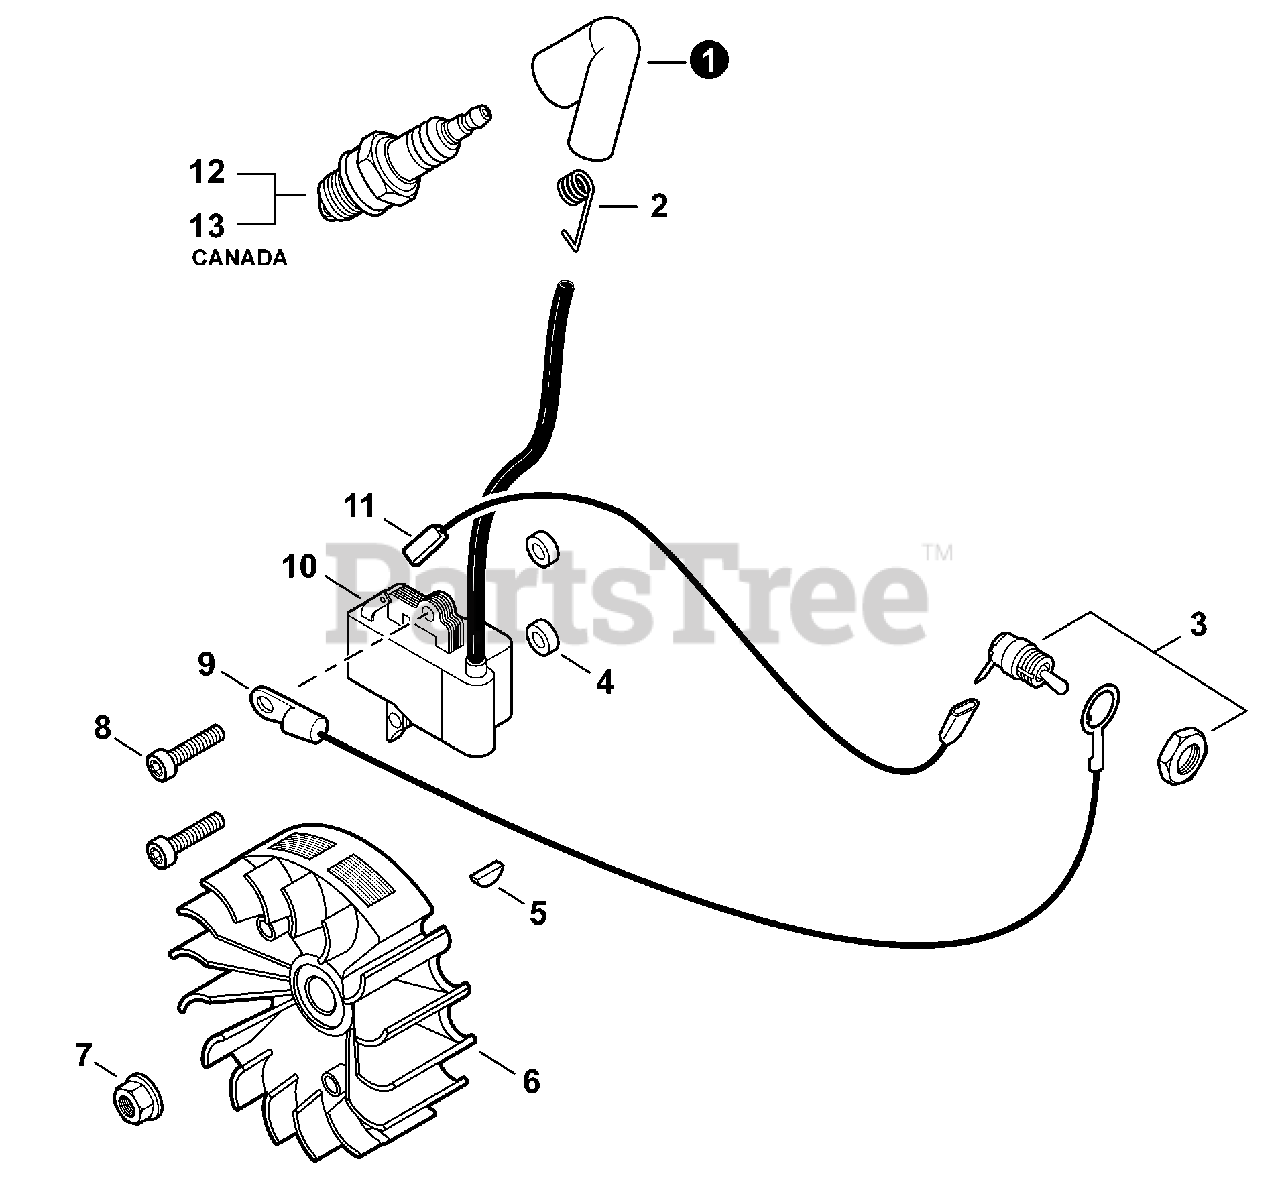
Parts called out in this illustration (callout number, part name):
1	CAP, SPARK PLUG
2	TERMINAL, SPARK PLUG
3	SWITCH, ON-OFF
4	WASHER 5.2×12×3
5	KEY, WOODRUFF
6	FLYWHEEL
7	NUT, FLANGE M8
8	BOLT, TORX 5×20
9	LEAD - GROUND L= 255
10	COIL, IGNITION
11	LEAD - IGNITION
12	SPARK PLUG - BPM8Y
13	SPARK PLUG - BPMR8Y
